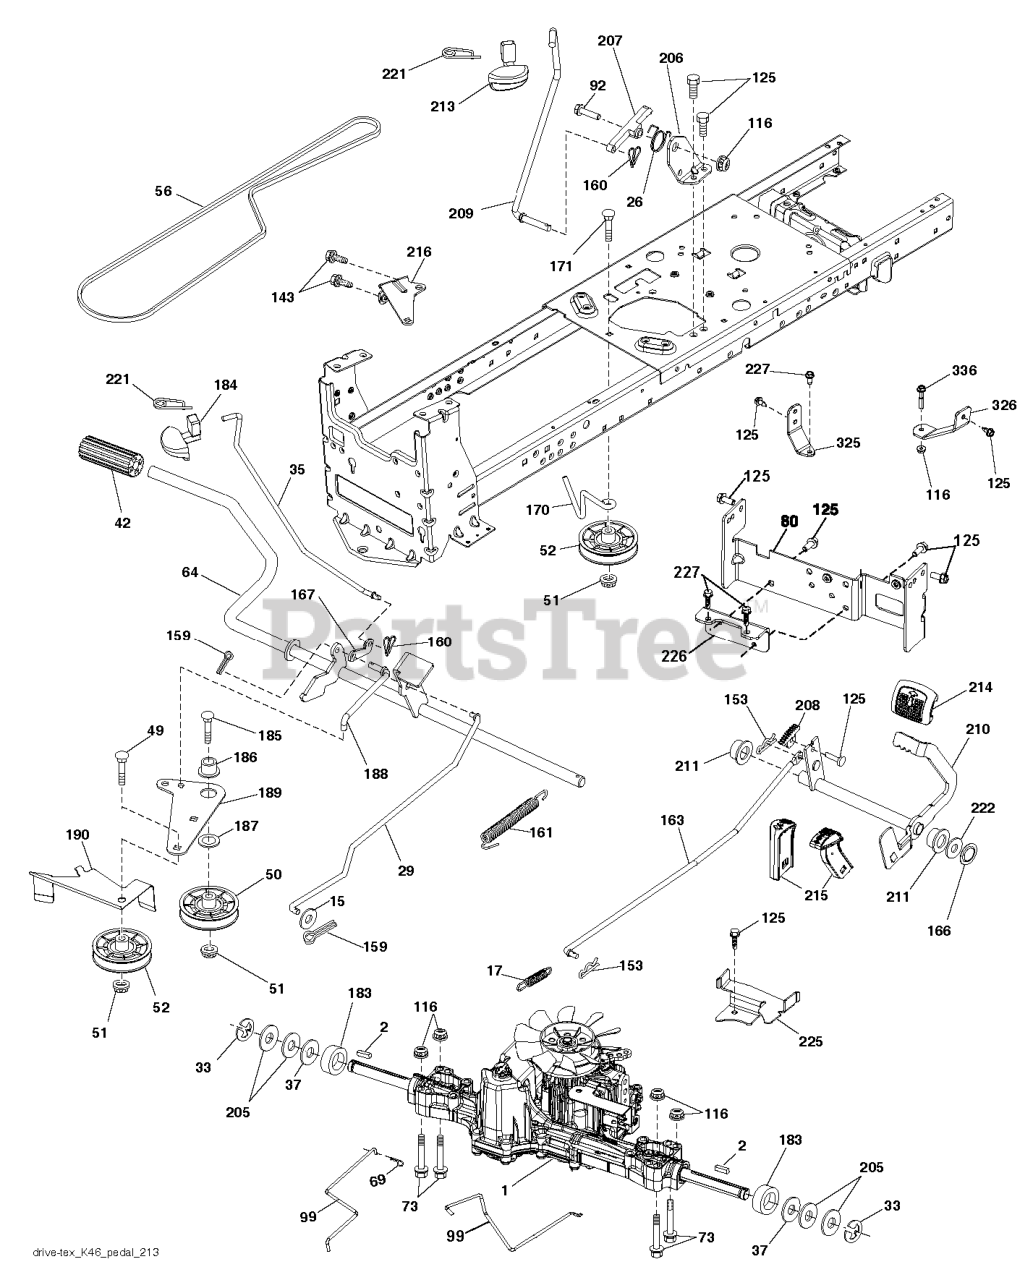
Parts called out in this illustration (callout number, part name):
2	SQUARE KEY
15	WASHER
17	SPRING.BRAKE.K46.GREEN
26	SPRING.RETURN.CRUISE
29	ROD.BRAKE.K46
35	ROD ROD.PARKINGBRAKE.GT.HUSQ/P
35	ROD .BRAKE. PARKING. GT. HUSQ.
37	WASHER.HARDENED
42	PEDAL COVER T
50	IDLER.FLAT.910.OFFSET
51	NUT LOCK FLG 3/8-16 UNC
52	IDLER.V-GROOVE.910.OFFSET
56	V-BELT.MOWER.92.40.42/K46
64	SHAFT.ASM.PEDAL.BRK.CNTR
69	HAIRPIN.SOFT.ZINC.059X1.125
80	STRAP.TORQUE.K46.K57R.TT
92	BOLT
99	ARM.PIVOTING.TCRD.GEN2.5.BAGGE
99	ROD.SPRING.BYPASS.K46.LT.Z
116	NUT LOCK HEX FLANGE 5/16-18
125	SCREW
143	SCR 5/16-18 X 1/2 SELFTAP ZN
153	RETAINER M
159	COTTER PIN
160	RETAINER CLIP
161	SPRING, RETURN LT
163	ROD.CONTROL.K57R.K46
166	NUT.PUSH.625
167	LATCH.BRAKE.SPRING
170	KEEPER.V-IDLER.CENTER.
183	SPACER AXLE
184	HANDLE.PARKING.BRAKE.H (BLK)
186	SPACER.RETAINER
187	WASHER 12/32X2X10GA
188	LINK.CLUTCH.GROUND DRIVE.LONG
189	BELLCRANK.GROUND.DRIVE.TEX.
190	KEEPER.BELLCRANK.DRIVE
206	BRACKET.MOUNT.CRUISE.LATCH
207	LATCH.CONTROL.CRUISE.TEX
208	GEAR.SECTOR.CONTROL.CR
209	ROD ROD.CRUISECONTROL.GT.HUSQ/
209	ROD.CONTROL.CRUISE.GT.
210	ROCKER.ASM.PEDAL.CONTR
211	BEARING.NYLON
213	KNOB.CONTROL.CRUSIE.HU
214	PEDAL.FORWARD.PAD.TEX
215	PEDAL.REVERSE.TEX.GT.4
215	PEDAL.COVER.REVERSE.CRD.X428BK
216	BRACKET.PULLEY.IDLER.W/TEX
221	RETAINER.SPRING.CLIP.H
222	WASHER 21/32 X 1-1/4 X 10 GA.
225	KEEPER.BELT.TRANSAXLE.K46
226	BRACKET.MOUNT.TORQUE.K46.TLT
227	SCREW.THDROL.5/16-18X3/4.TTY
325	BRCKT.PNT.TRQ.STP.46.20TIRE.RH
325	BRACKET.TRQ.STP.46.20".TIRE.LH
326	BRCKT.PNT.TRQ.STP.46.20TIRE.RH
326	BRACKET.TRQ.STP.46.20".TIRE.LH
336	BOLT.5/16-18X1-3/4.FLANGED.HEX
